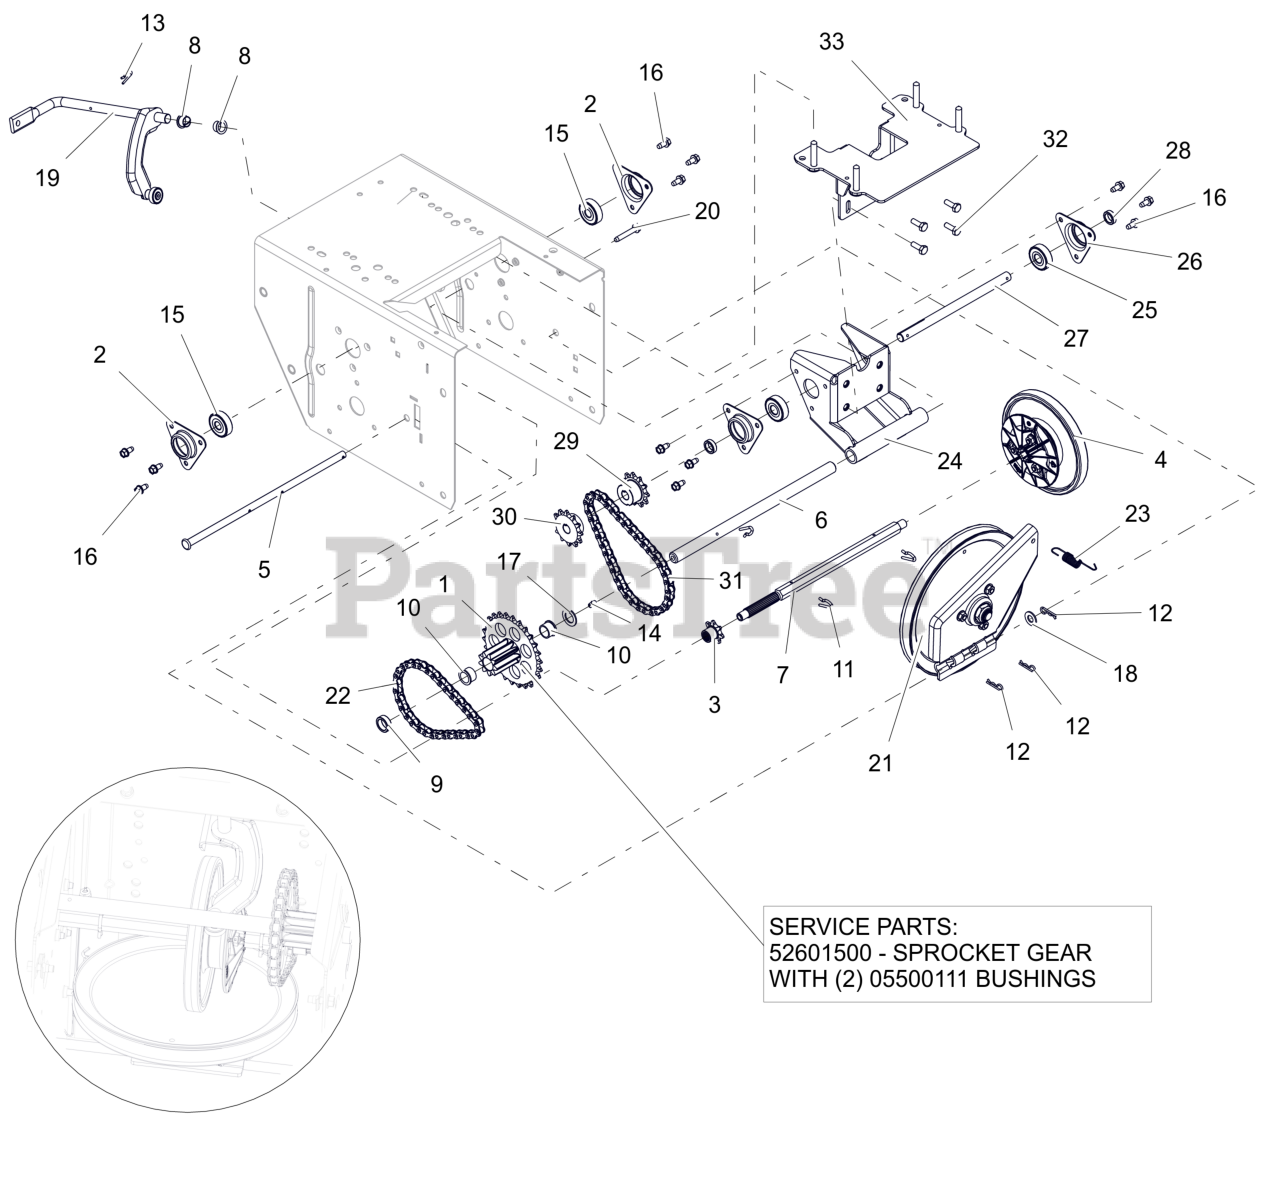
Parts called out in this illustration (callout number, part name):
1	PINION & SPROCKET
1	PINION & SPROCKET W/BUSHINGS
2	FLANGE, BEARING
3	SPROCKET, PINION 7T W/SPLINE
4	DISC, FRICTION DRIVE-ASSEMBLY
5	PIN, PIVOT
6	SHAFT, PINION-HARDENED
7	SHAFT, HEX HEAT TREATED SPLINE
8	BUSHING, POLYLINER-.50 SPLIT
9	BSHG-SLV, .635X.880X.305
10	BSHG-FLG .625X.750X.500X.875
11	PIN, SPRING CLIP
12	PIN, HAIR #213 .08X1.19 ZCC
13	CLIP, SPRING
14	ZERK,FITTING .25X.125 DRIVE IN
15	BRG-BALL .437X1.375X.437
16	SCR-TAP .25-20X.50 HWH ZCC
17	WSHR, FLT .630X1.005X.062 ZCC
18	WSHR,FLT .406X.812X.065 ZCC
19	ARM, SHIFT - ASSEMBLY
20	SCR,TAP .25-20X1.50 HWH TR ZCC
21	PLATE, SWING ASSEMBLY-DEEP
22	CHAIN - #41, 32 PITCHES
23	SG-TENS .048X.50X2.8
24	WLDMT, TRIPLE REDUCTION BRKT
25	BRG-BALL .500X1.38X.437
26	FLANGE, BEARING
27	SHAFT, REDUCTION HEAT TREATED
28	SPCR, SLV
29	SPROCKET, 11 TOOTH
30	SPROCKET, 12 TOOTH
31	CHAIN, ROLLER - #41X36 PITCHES
32	BLT, HEX .25-20X.75 G5 ZCC
33	STRAP, TRIPLE REDUCTION MEDIUM
